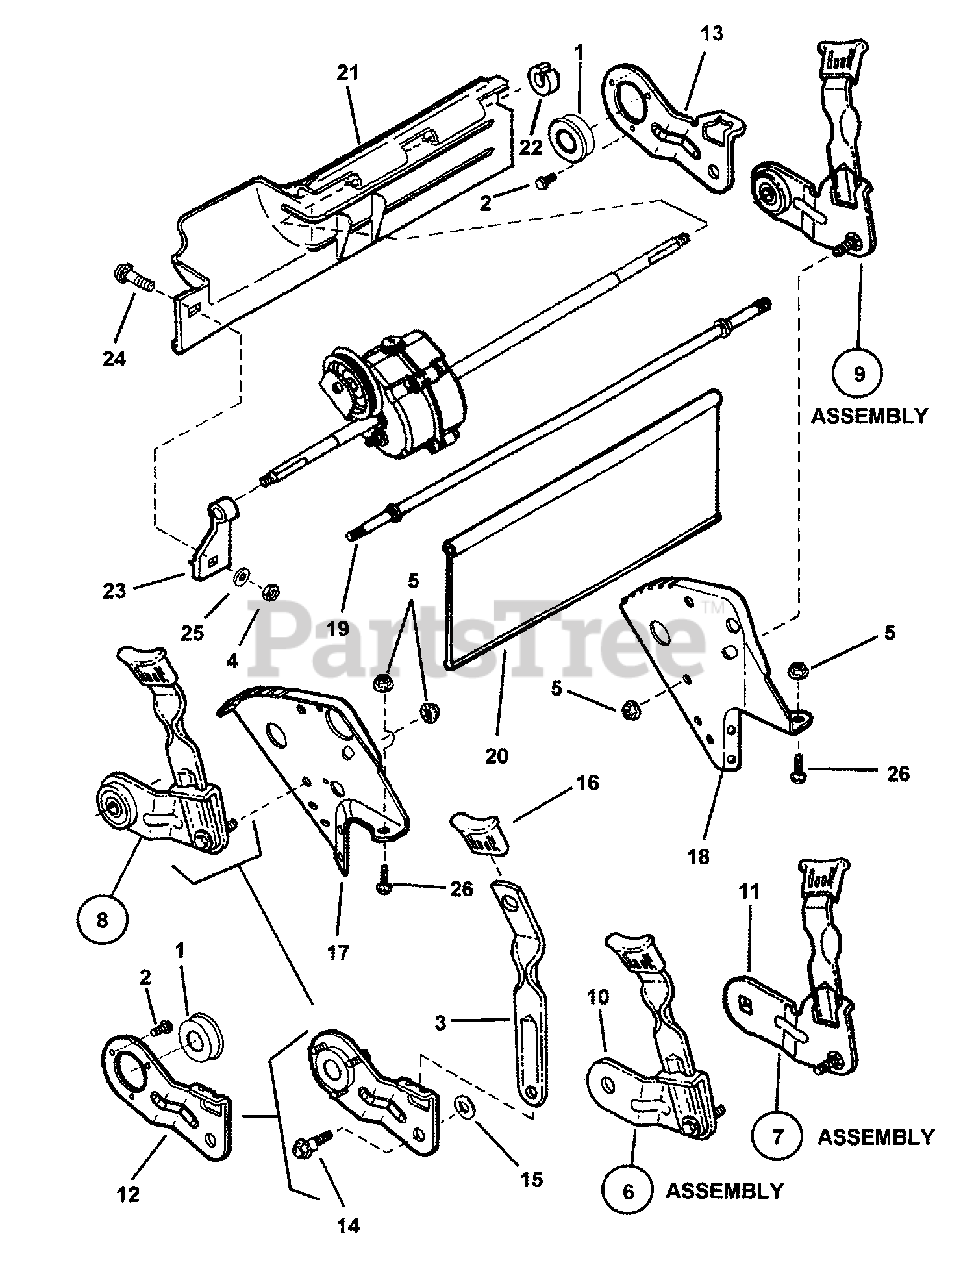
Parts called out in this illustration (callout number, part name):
1	BALL BEARING, 9/16" I.D.
2	SCREW, #10-32 x 3/8" Hex Washer Self-Tap
3	LATCH, Height Adjusting (Long)
4	NUT, 1/4-20 Hex
5	NUT, 5/16-18 Hex Flange Lock, GR5
6	ASSEMBLY, Wheel Arm, Right Rear (Round hole)
7	ASSEMBLY, Wheel Arm, Left Rear (Square hole)
8	ASSEMBLY, Wheel Arm (Right Rear)
9	ASSEMBLY, Wheel Arm (Left Rear)
10	ARM, Round Axle End, Right Rear (Round hole)
11	ARM, Square Axle End, Left Rear (Square hole)
12	ARM, Wheel, Right Rear
13	ARM, Wheel, Left Rear
14	BOLT, 5/16-18 x 1" Shoulder
15	RETAINER, 5/16" Bolt
16	GRIP, Latch
17	BRACKET, Right Rear Wheel
18	BRACKET, Left Rear Wheel
19	AXLE
20	GUARD, Rear Foot
21	GUARD, Rear Foot
22	RING, Split (Black)
23	SUPPORT, Foot Guard
24	BOLT, 1/4-20 x 1/2" Short Neck Carriage GR5
25	WASHER, 1/4" Internal Tooth Lock
26	BOLT, 5/16-18 x 1/2" Short Neck Carriage GR5
